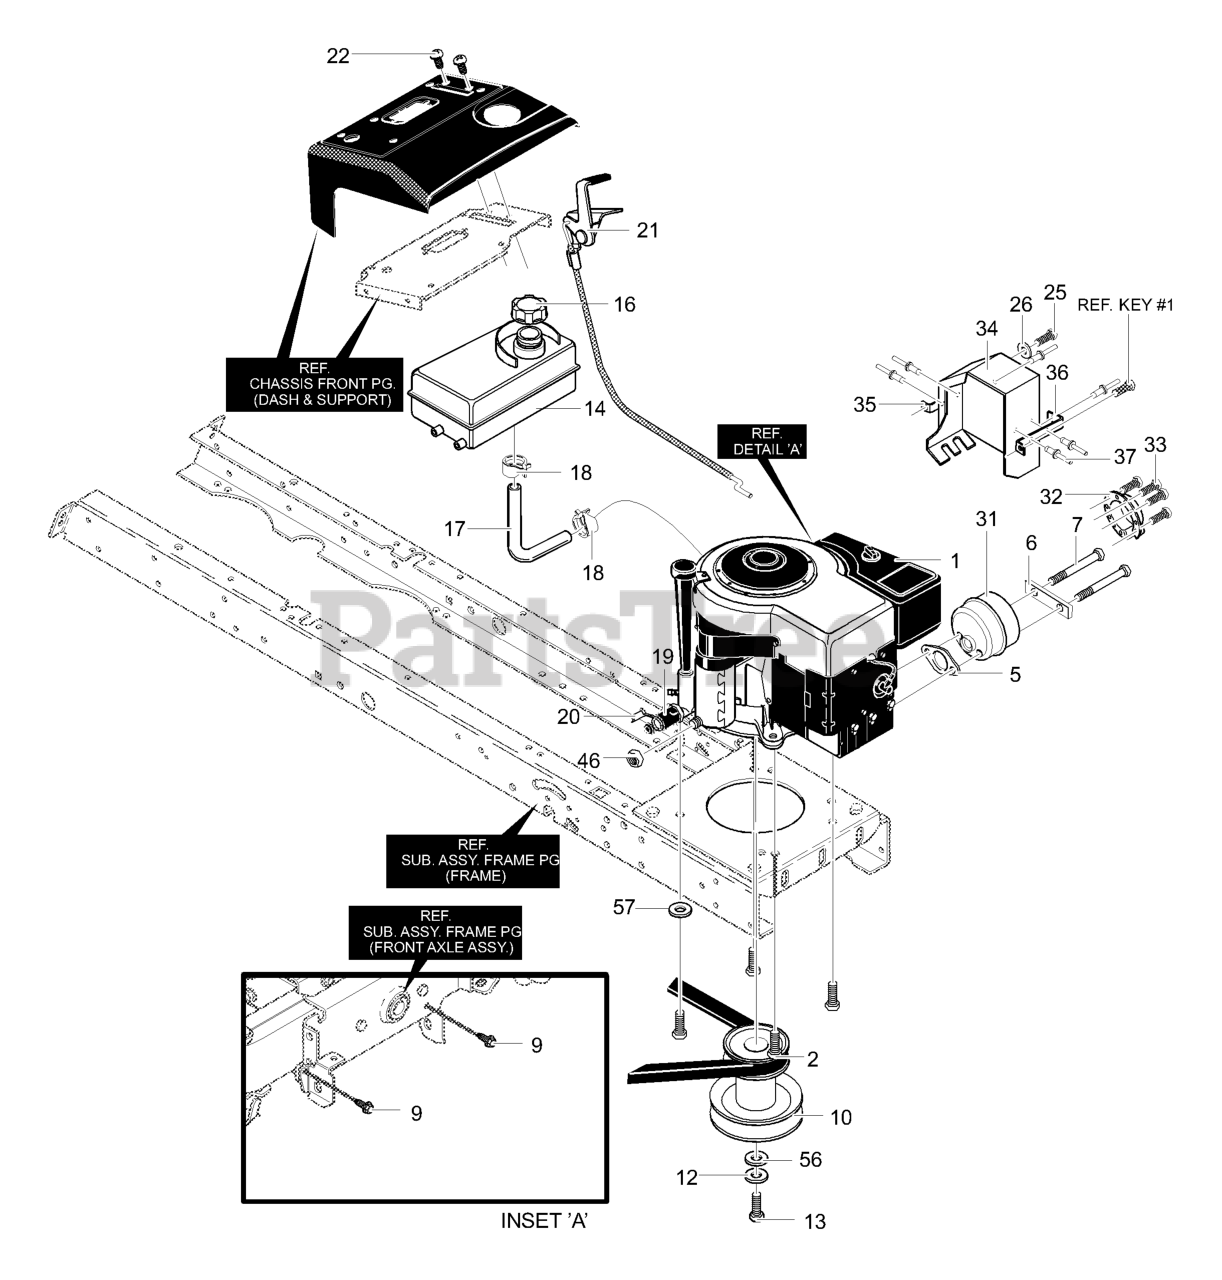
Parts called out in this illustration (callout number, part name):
1	13HP Engine
2	Engine Bolt 3/8x1.25
5	Muffler Gasket
6	Lock Bracket
7	SCREW, 5/16-18 x 4.125
9	SCREW, 5/16-18 x 0.75
10	Stack Pulley
12	WASHER, Regsptlk
13	BOLT, 7/16-20x1.75LG
14	Fuel Tank 1.4 Gal.
16	Fuel Cap
17	Tubing 14.50 Inches
18	Clamp, Fuel
19	Oil Drain Valve Assembly
20	Cap, Oil Drain Valve
21	Throttle Control
22	SCREW, #8-16x.38
25	SCREW, 1/4 20x.50
26	WASHER (18x32)
31	Muffler
32	Deflector, Exhaust
33	SCREW, #8-32x.38
34	Heat Shield
35	L-Bracket
36	L-Bracket
37	Pop Rivet
46	NUT, 1/4-20 Reghexjam
56	WASHER, Flat
57	WASHER, Exlk
